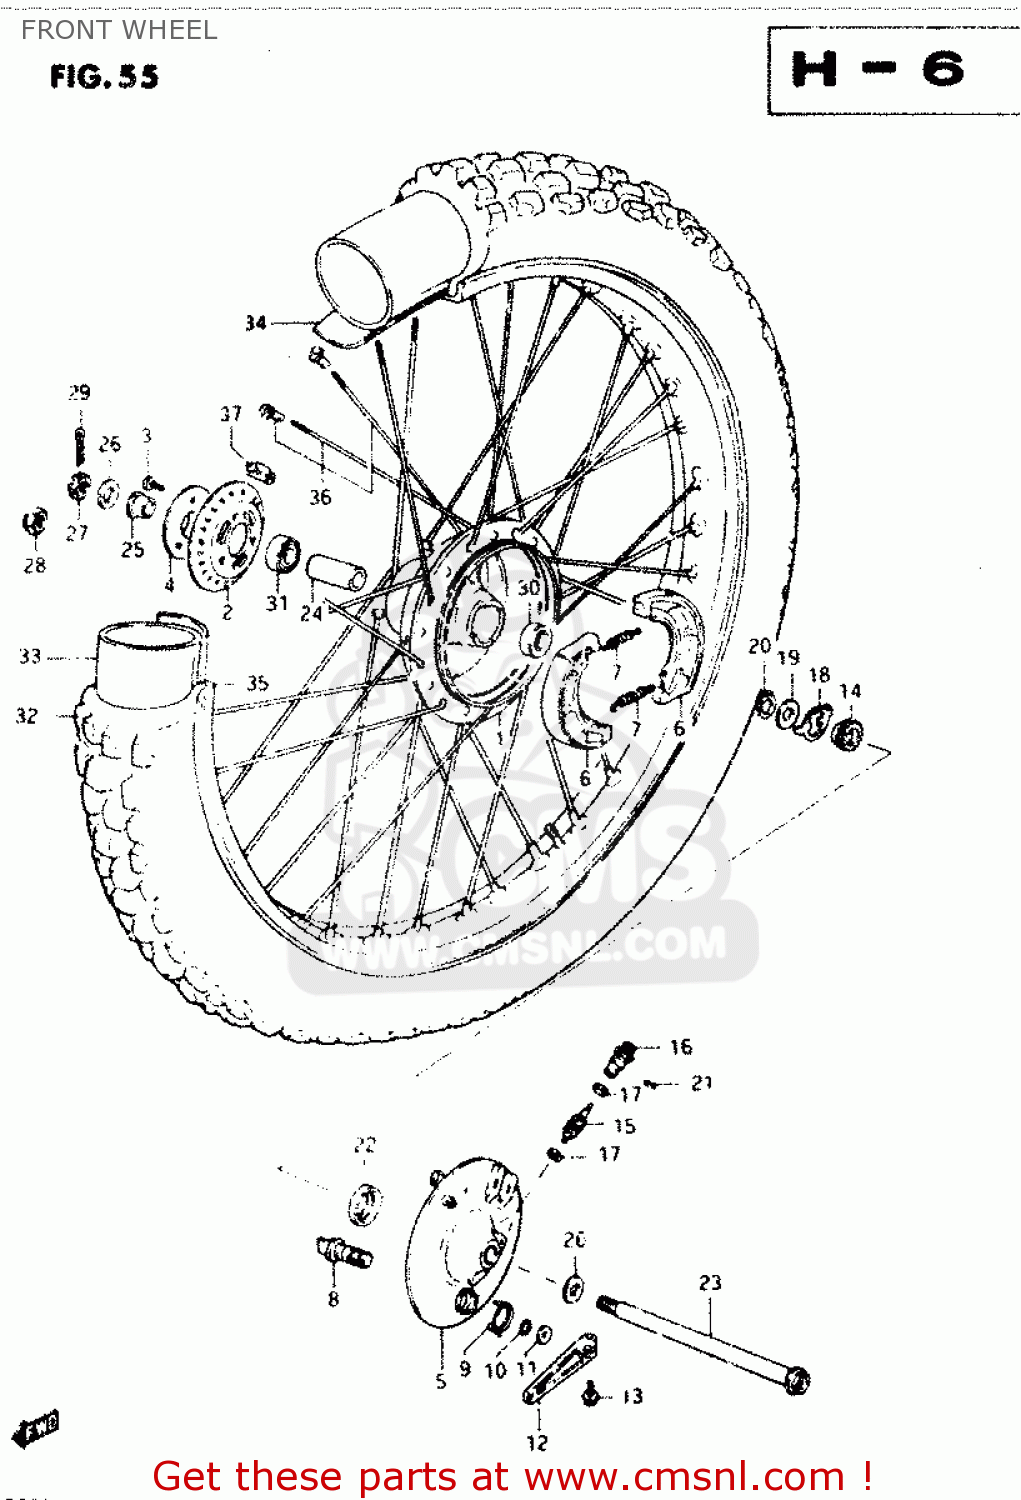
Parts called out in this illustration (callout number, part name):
1	HUB,FRONT
2	FLANGE,FR HUB,R
3	BOLT
4	PLATE,FRONT HUB BEARING
5	PANEL,FRONT HUB
6	SHOE,BRAKE (NAS)
7	SPRING(L:34)
8	CAM,BRAKE
9	SPRING
10	O-RING (D:2.4 ID:13.8)
11	WASHER (14.5X22X1.6)
12	LEVER,FRONT BRAKE CAM
13	BOLT
14	GEAR,SPEEDOMETER
15	PINION,SPEEDOMETER
16	BUSH,METER GEAR OUTER
17	WASHER (5.1X9X0.4)
18	DRIVER,SPEEDOMETER GEAR
19	WASHER(18.5X24X1)
20	CIRCLIP
21	SCREW
22	OIL SEAL (43X58X7)
23	AXLE,REAR
24	SPACER (12.6X19X52)
25	SPACER,FR AXLE,R
26	WASHER
27	NUT, REAR AXLE
28	NUT 12MM
29	COTTER PIN
30	BEARING
31	BEARING, RH
32	TIRE,FRONT
33	TUBE
34	PROTECTOR,WHEEL,INNER
35	RIM,FRONT WHEEL
36	SPOKE SET,FRONT
37	BALANCER,WHEEL (50G)
